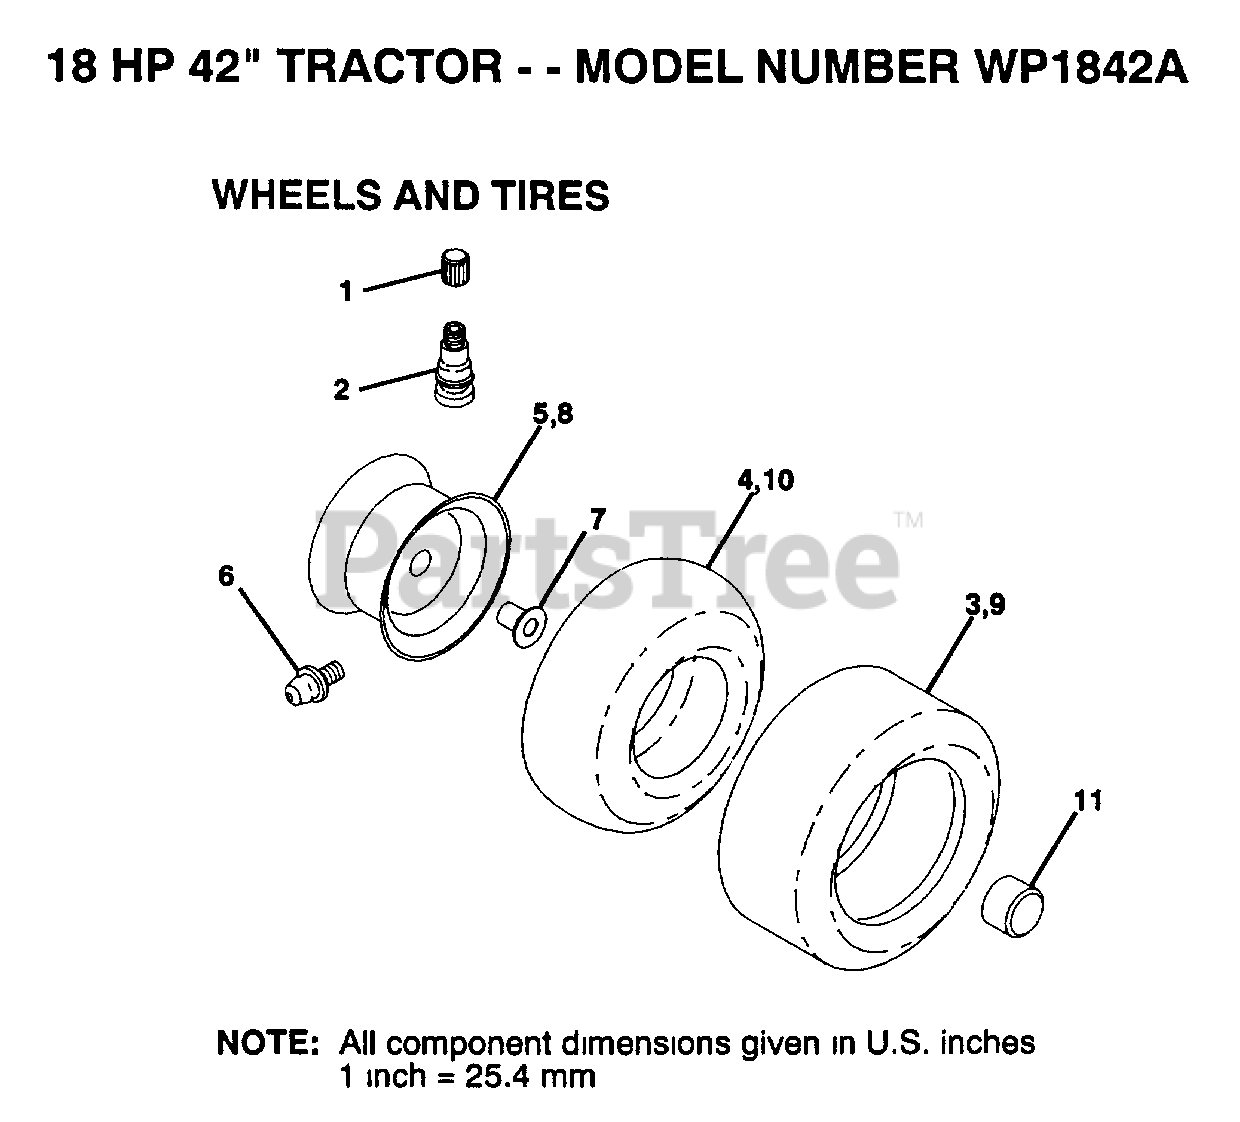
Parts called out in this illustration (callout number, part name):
1	VALVE CAP
2	VALVE STEM LT
4	TUBE.5.3/4.5/6
6	FITTING LT
7	"FLANGE, BEARING"
10	TUBE.18X9.5-8
11	HUB CAP
